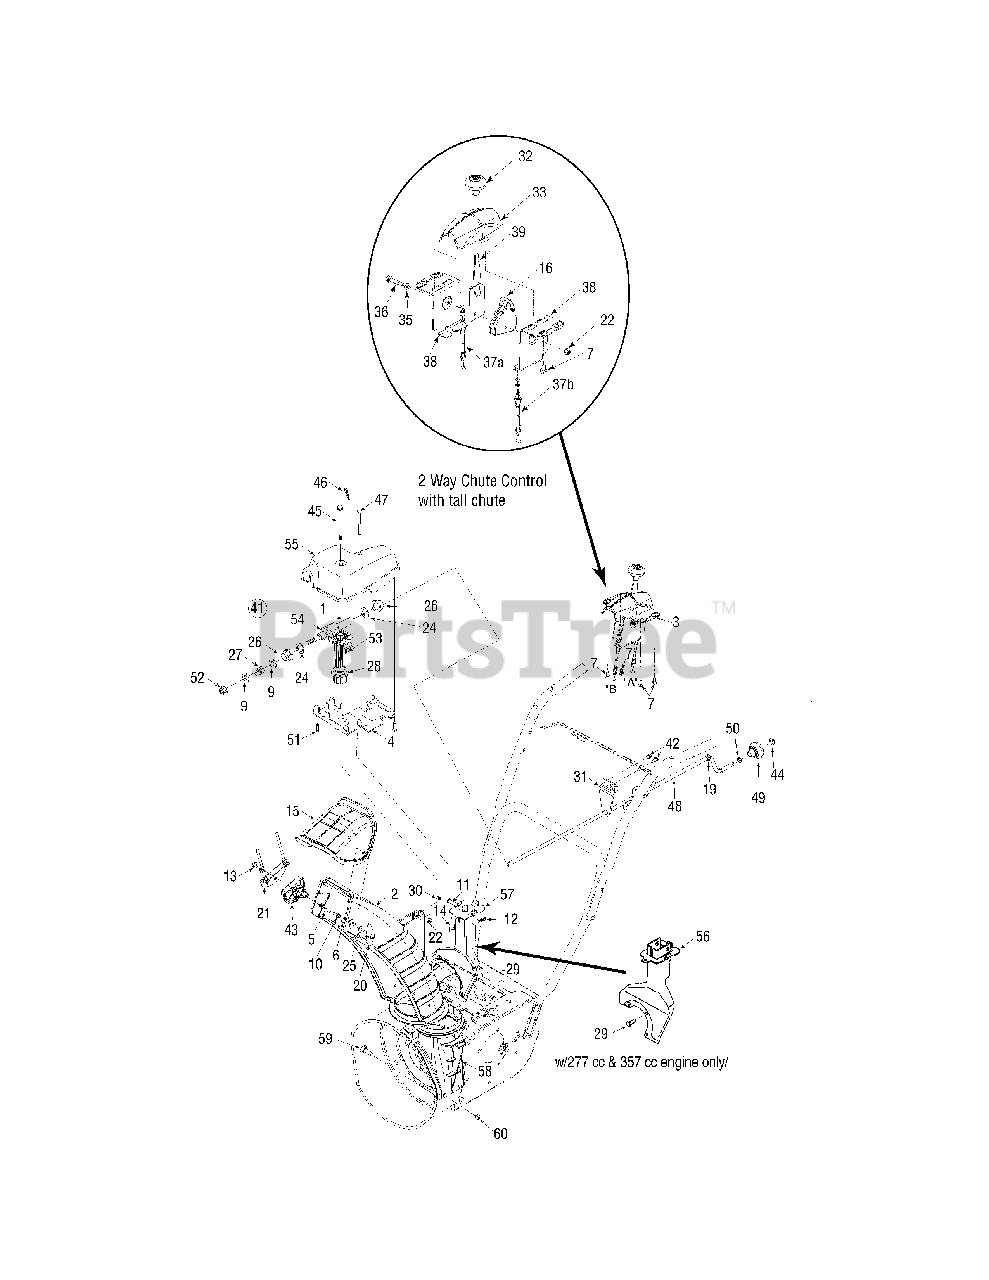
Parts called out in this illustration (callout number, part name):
1	Hex Shaft
2	Tall Lower Chute
3	2 Way Chute Control Assembly
4	Chute Gear Ro ta tion Bracket
5	Carriage Bolt 5/16-18 x 1.50 Gr. 2
6	Carriage Screw 5/16-18 x 1.0
7	Hi-Lo Screw 1/4-15 x .5
9	Flat Washer .38 x .92 x .110
10	Hex Tapp Scr 1/4 x .75" Lg.
11	Clevis Pin 3/8 x 1.87
12	Bow Tie Cotter Pin
13	Flange Locknut 5/16-18 Gr. F Nylon
14	Wing Nut 1/4-20
15	Upper Chute w/Ex port Label, Remote
20	Handle Knob Assembly
22	Hex L-Flanged Nut 1/4-20 Gr. F Nylon
24	Flat Washer .625 x 1.0 x .067
25	Flat Washer .349 ID x .879 OD x .063
26	Hex Flg. Bearing
27	Compression Spring .39 x .60 x .88
28	Hex Bearing
29	Hex Hd. Cap Screw 5/16-24 x .75
30	Flat Washer .25 ID x .63 OD x .0515 HT.
33	Control Cover - 2 Way
35	Spring Washer .390 x .625 x .012
36	Flg Shlder Screw .310 x .995: 1/4-20
41	Gear box Assembly
42	Hex Wash Hd TT Scr. 1/4-20 x .625
44	Push Nut 3/8" Rod
45	Flg. Shoulder Screw .312 x 3.5: 1/4-20
46	Internal Cotter Pin
47	Hex. Hd. Cap Scr. 1/4-20 x 3.0 Gr. 5
48	Chute Crank .375 Dia. x 30.5" Lg.
50	Flat Washer .375 x .738 x .063
51	Hi-Lo Screw #12-16 x .75
52	Hex L-Flanged Nut 3/8-16 Gr. F Nylon
53	Gear 14 teeth helical w/hub
54	Worm - Nylon
55	Cover
56	Chute Sup. Bkt. Ass'y (w/277 cc & 357 cc engines only)
57	Chute Support Bracket Ass'y
58	Chute Adapter
59	Carriage Screw 1/4-20 x .75 Gr. 5
60	Hex L-Flanged Nut 1/4-20 Gr. F Nylon
